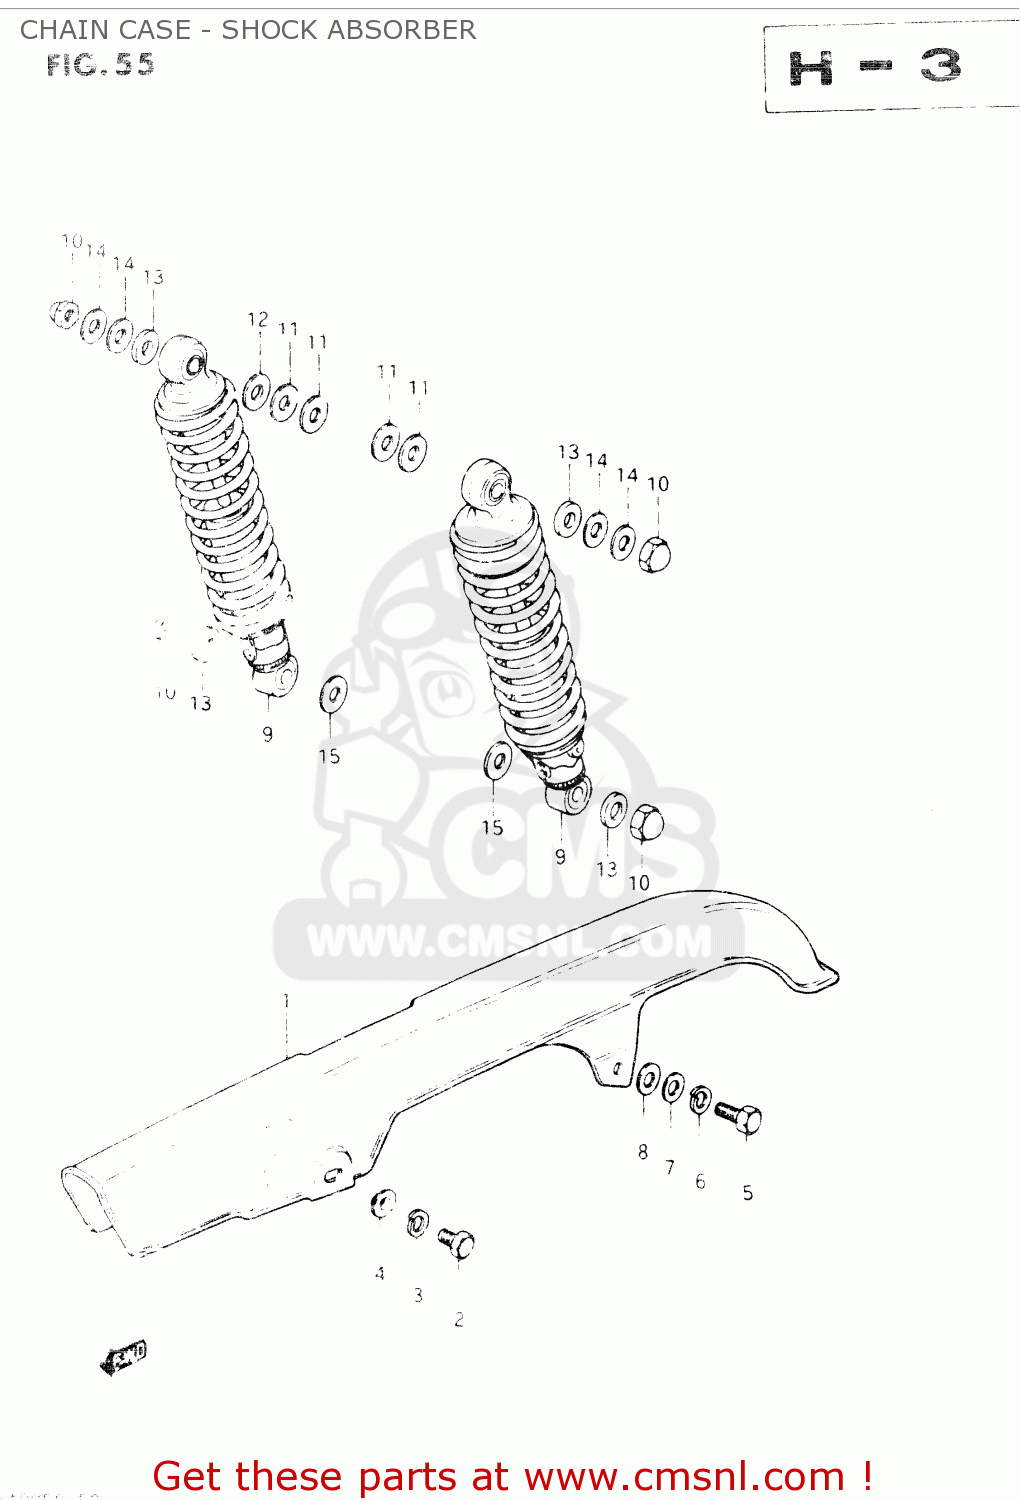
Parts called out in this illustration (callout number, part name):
1	CASE,CHAIN
2	BOLT
3	WASHER,LOCK
4	WASHER,LOCK
5	BOLT
6	WASHER,LOCK
7	WASHER
8	WASHER(6.5X18X1)
9	ABSORBER ASSY,RR SHOCK
10	NUT, LOWER LH
11	WASHER
12	WASHER (12.5X24X3.2)
13	WASHER
14	WASHER(10.5X24X3.2)
15	WASHER (12.5X24X1.6)
